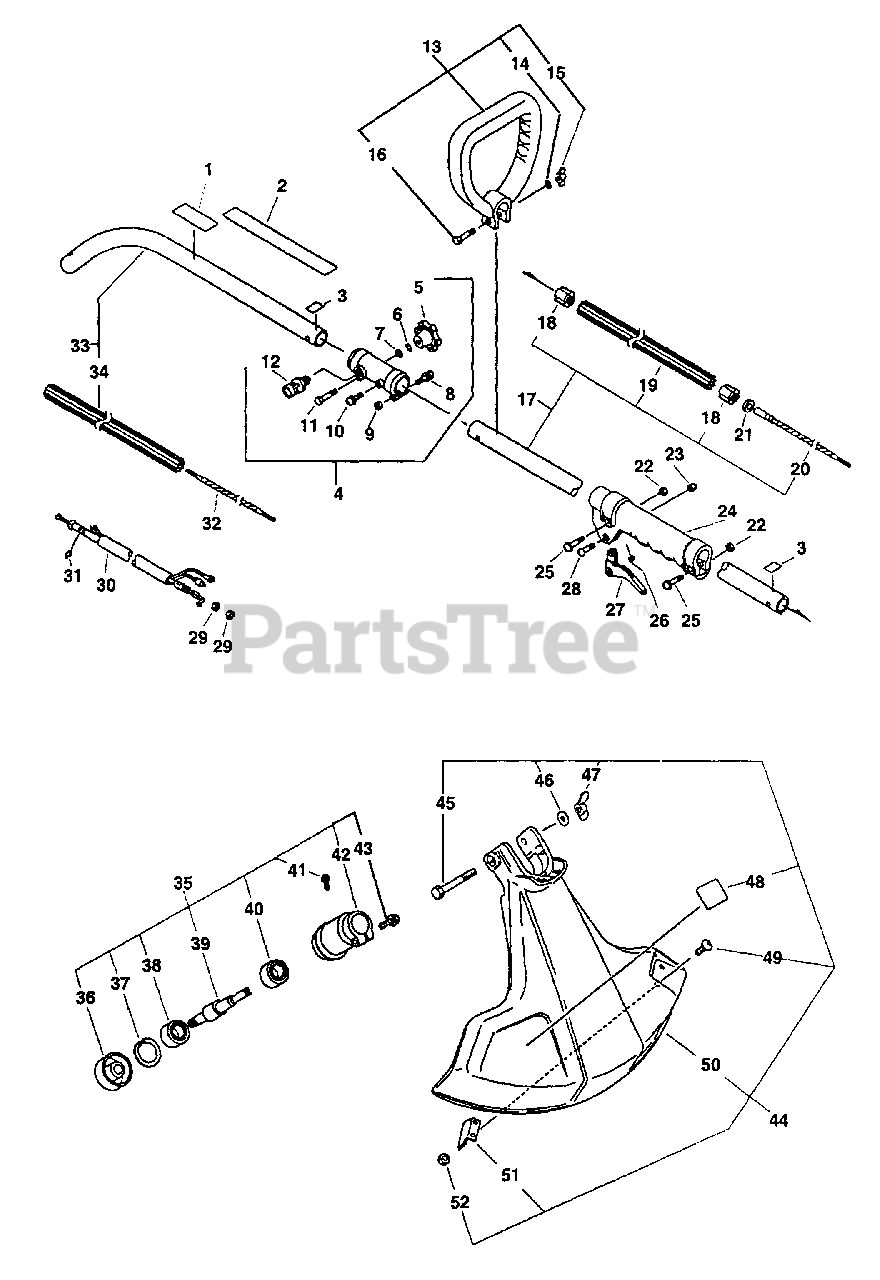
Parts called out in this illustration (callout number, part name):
1	LABEL - CAUTION
2	LABEL - CAUTION
3	LABEL - ALIGNMENT
4	CLAMP, MAIN PIPE
5	KNOB, FASTENER
6	LOCKWASHER - 5
7	WASHER - 5
8	SCREW - 5X30
10	SCREW - 5X12
11	BOLT - 5X35
12	LATCH ASSY
13	HANDLE ASSY - FRONT
14	WASHER - 1/4"
15	WINGNUT - 1/4-20
16	BOLT - 1/4-20 X 1-1/2"
17	MAIN PIPE ASSY
19	LINER - FLEXIBLE
20	DRIVESHAFT - FLEXIBLE -- UPPER
21	BUSHING
23	LOCKNUT - 5
24	GRIP, HANDLE
25	SCREW - 5X25
26	SPRING, TRIGGER
27	TRIGGER, THROTTLE
28	SCREW - 5X30
30	CABLE, THROTTLE
31	RING, RETAINING - 4
32	DRIVESHAFT - FLEXIBLE
33	MAIN PIPE ASSY
34	LINER - FLEXIBLE
35	GEAR CASE ASSY
36	ADAPTOR, BLADE - UPPER
37	RING, RETAINING - 30
38	BEARING, BALL - 6200
39	GEAR - SHAFT
40	BEARING, BALL - 6200
41	SCREW - 4X10
42	CASE, GEAR
43	BOLT - 5X25
44	DEBRIS SHIELD KIT
45	BOLT - 1/4-20 X 2"
46	WASHER - 1/4"
47	WINGNUT - 1/4-20
48	LABEL - CAUTION
49	SCREW - 5X16
50	SHIELD, DEBRIS - PLASTIC
51	KNIFE, TRIMMER LINE
